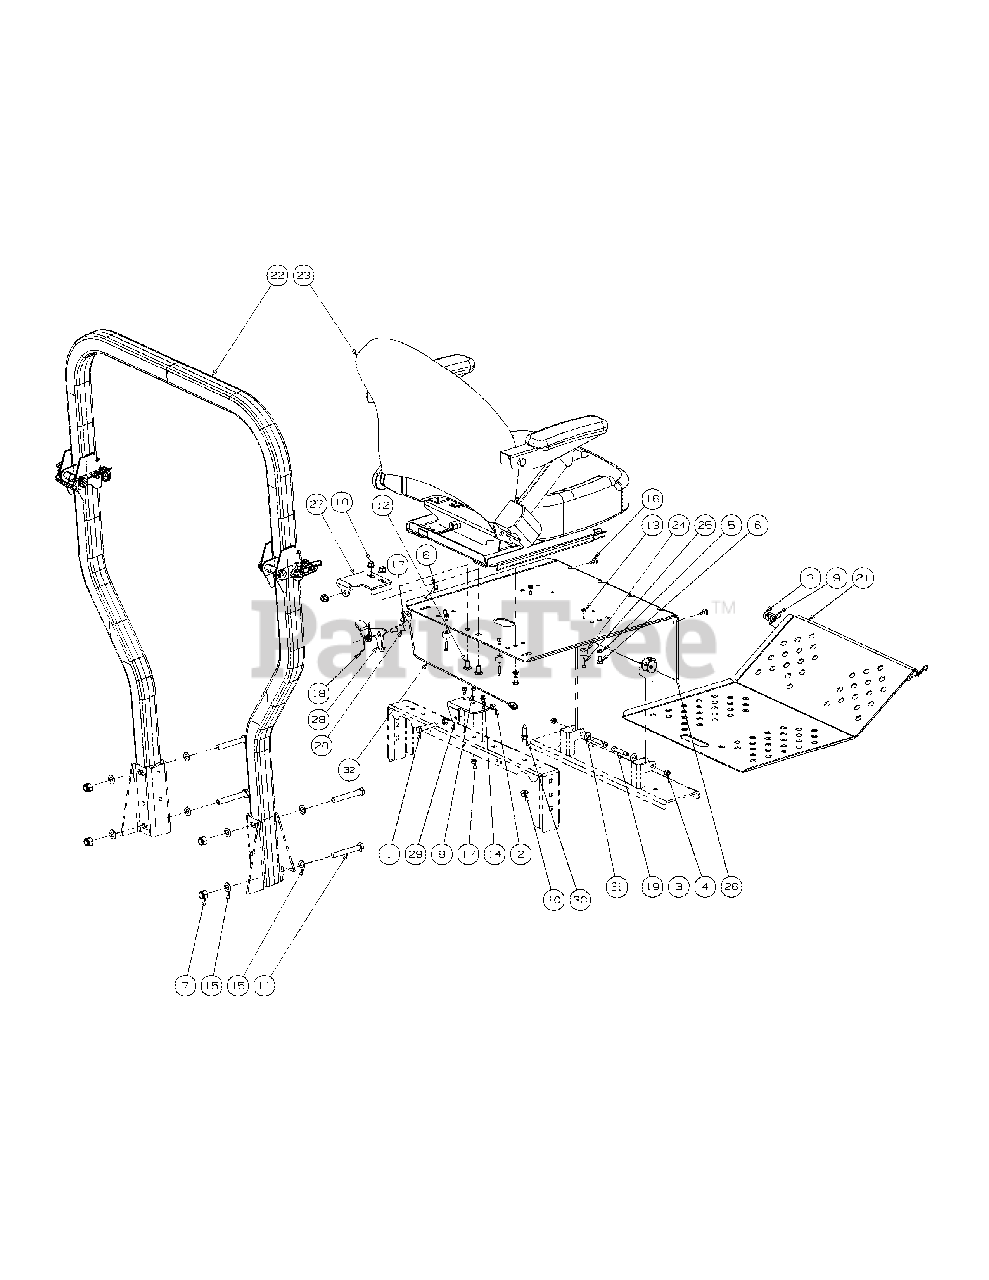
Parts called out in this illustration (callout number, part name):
1	Hex Cap Screw 3/8-16 x 2.00
2	Hex Nut, 3/8-16
4	Flange Lock Nut, 5/16-18
5	Lock Washer, 5/16
6	Hex Cap Screw, 5/16-18 x 1/2
7	Nut, 1/2-13, Nylon Insert
8	Screw, Hex, Cap, 1/4-20 x .75
9	Hair Pin, 3/8-1/2
10	Flange Lock, Hex Nut, 3/8-16
11	Hex Cap Screw, 1/2-13 x 3.50
12	Carriage Bolt, 3/8-16 x .75 Long
13	Nut, #10-24, Nylon Lock
14	Screw, TT, 1/4-20, 0.5, Hex Index Washer
15	Washer, .536 ID x .930 OD x .05
16	Rubber Bumper, .62 OD x .22 Thick
17	Lock Nut, 1/4-20
18	Deck Lift Spring, Left Hand
19	Shoulder Bolt, .375 x 1.50
20	Shoulder Bolt, 1/2 x 3/4, 3/8-16
21	Floor Panel Assembly
22	Foldable Rops Assembly
23	Seat w/ Seat Belt & Suspension
24	Rubber Stop with Washer
25	Standard Cap Screw, #10-24 x .75
26	Seat Plate Assembly
27	Seat Latch Bracket
28	Latch Lever Bracket
29	Latch Bracket
30	Adjustable Stud
31	Flat Washer, .406 ID, 1.0 OD, .105
32	Cable Support
